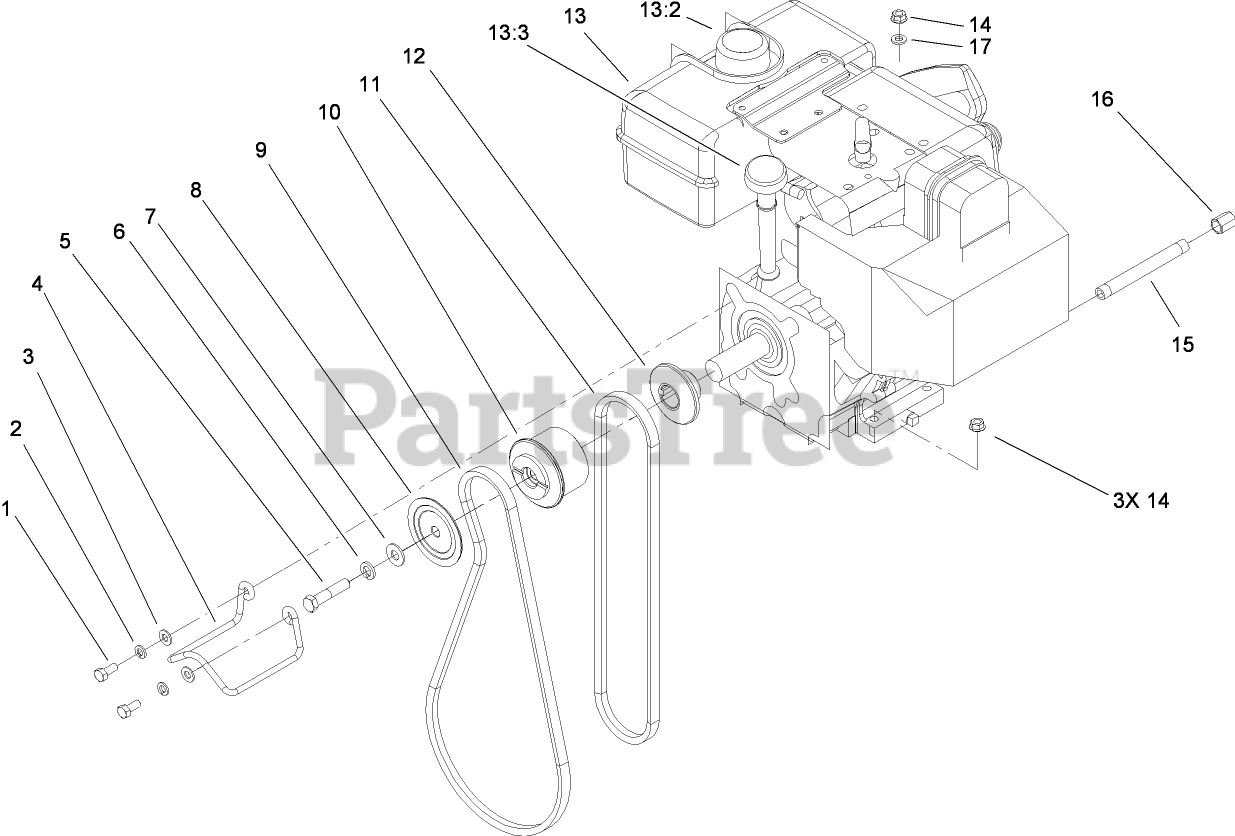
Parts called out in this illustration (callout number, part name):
1	SCREW-HH
2	WASHER-LOCK
3	WASHER-PLAIN
5	SCREW-HH
6	WASHER-LOCK
7	WASHER-FLAT
8	SHEAVE-HALF, IMPELLER
9	BELT-V
10	PULLEY-ENGINE, CENTER
11	V BELT-TRACTION
12	SHEAVE-HALF, TRACTION
13	Loose Parts Package
13:3	DIPSTICK
14	NUT-HF
15	NIPPLE-PIPE
16	CAP-PIPE
17	WASHER-FLAT
